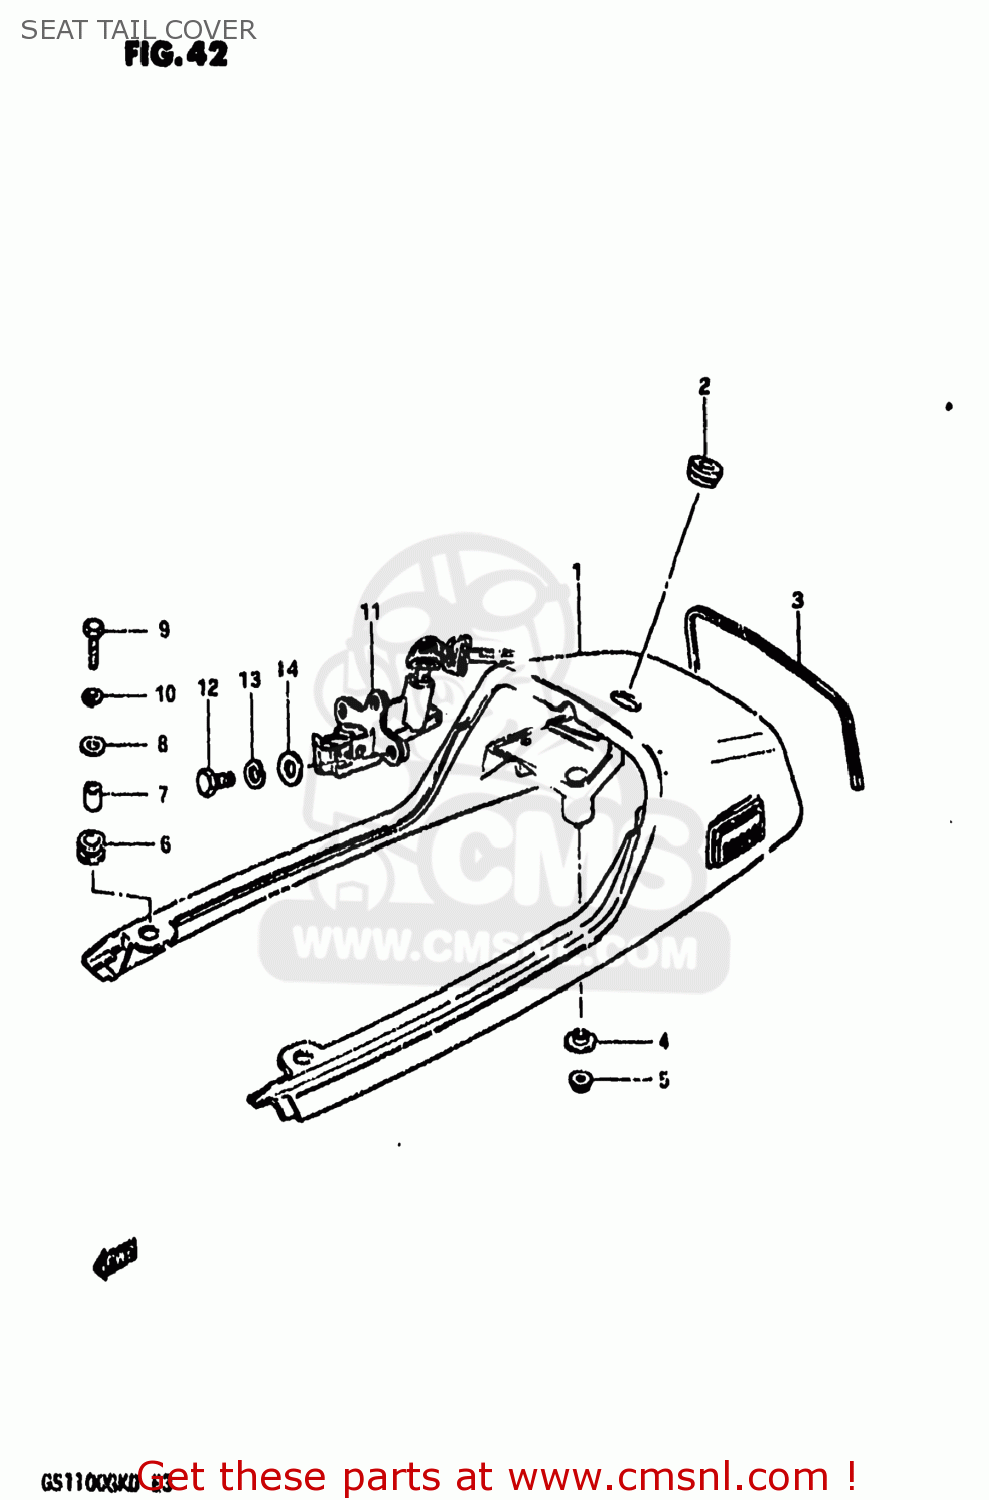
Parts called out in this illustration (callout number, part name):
1	COVER SET,SEAT TAIL
2	GROMMET,SEAT LOCK HOLE
3	MOLDING,SEAT TAIL COVER
4	WASHER
5	NUT 6MM
6	CUSHION
7	SPACER (7X10X12)
8	WASHER (6.5X24X1.6)
9	BOLT
10	LOCK WASHER
11	LOCK SET,SEAT
12	BOLT
13	LOCK WASHER
14	WASHER
